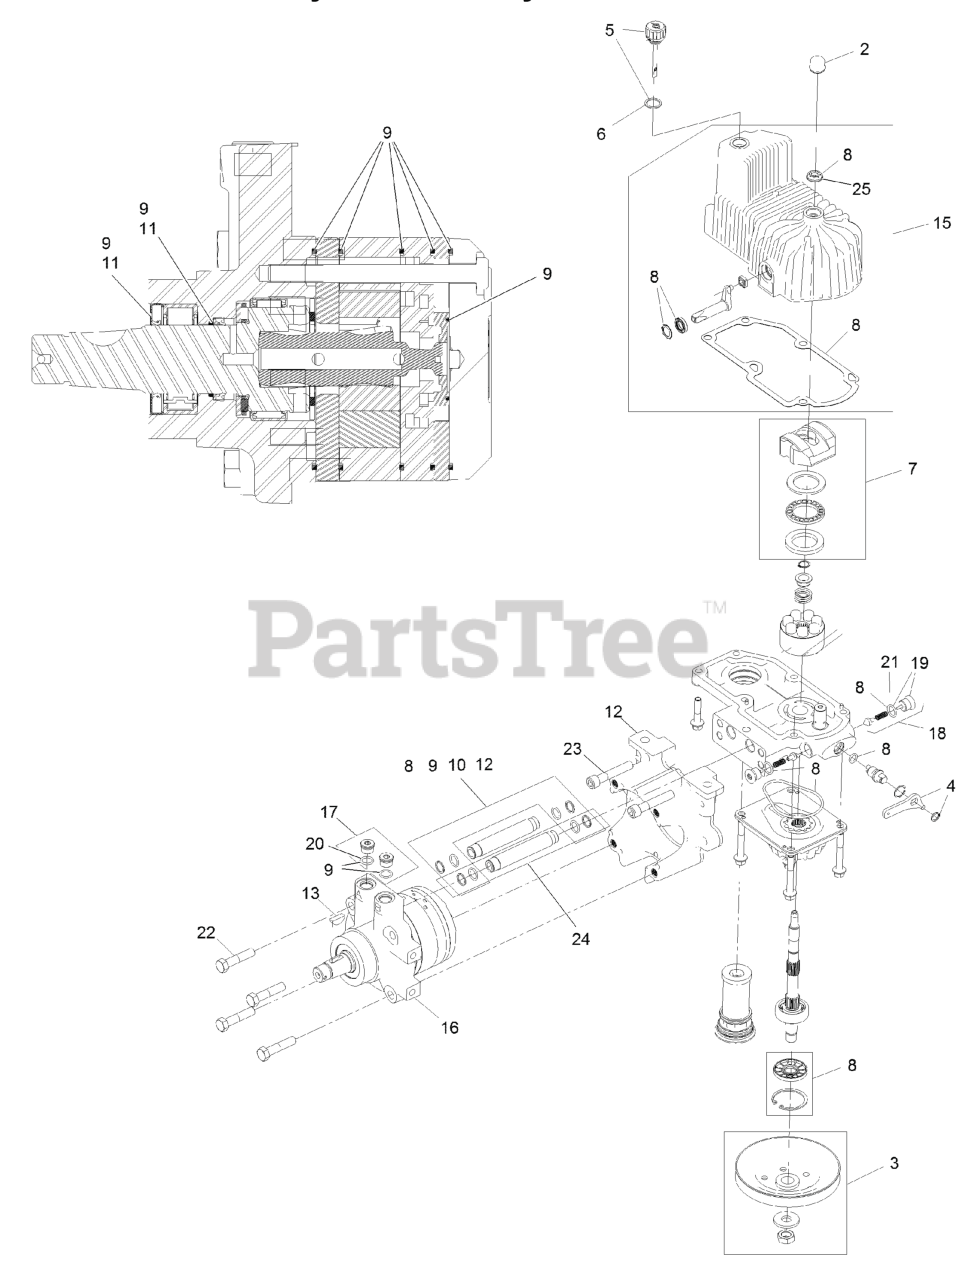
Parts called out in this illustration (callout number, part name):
2	COVER-SHAFT, HYDRO
3	PULLEY KIT
4	HANDLE-BYPASS VALVE, HYDRO
5	DIPSTICK-HYDRO W/GASKET
6	GASKET-DIPSTICK, HYDRO
7	SWASH BLOCK KIT
8	PUMP SEAL KIT
9	MOTOR SEAL KIT
10	TUBE SEAL KIT
11	OUTPUT SHAFT SEAL KIT
12	NOSE CUP-UHT
13	KEY-WOODRUFF
15	HOUSING-HYDRO, LH
16	MOTOR-HYDRAULIC LH 240CC
17	MAGNETIC PLUGS SERVICE KIT
18	CHECK VALVE ASM
19	PLUG-CHECK (W/O-RING)
21	O-RING-CHECK VALVE
22	SCREW HH
23	SCREW-HSH
24	HYDRAULIC TUBE KIT
25	SEAL-FAN DRIVE
26	KIT, PUMP SECTION 12CC LH NO FAN
27	ROTATING KIT
